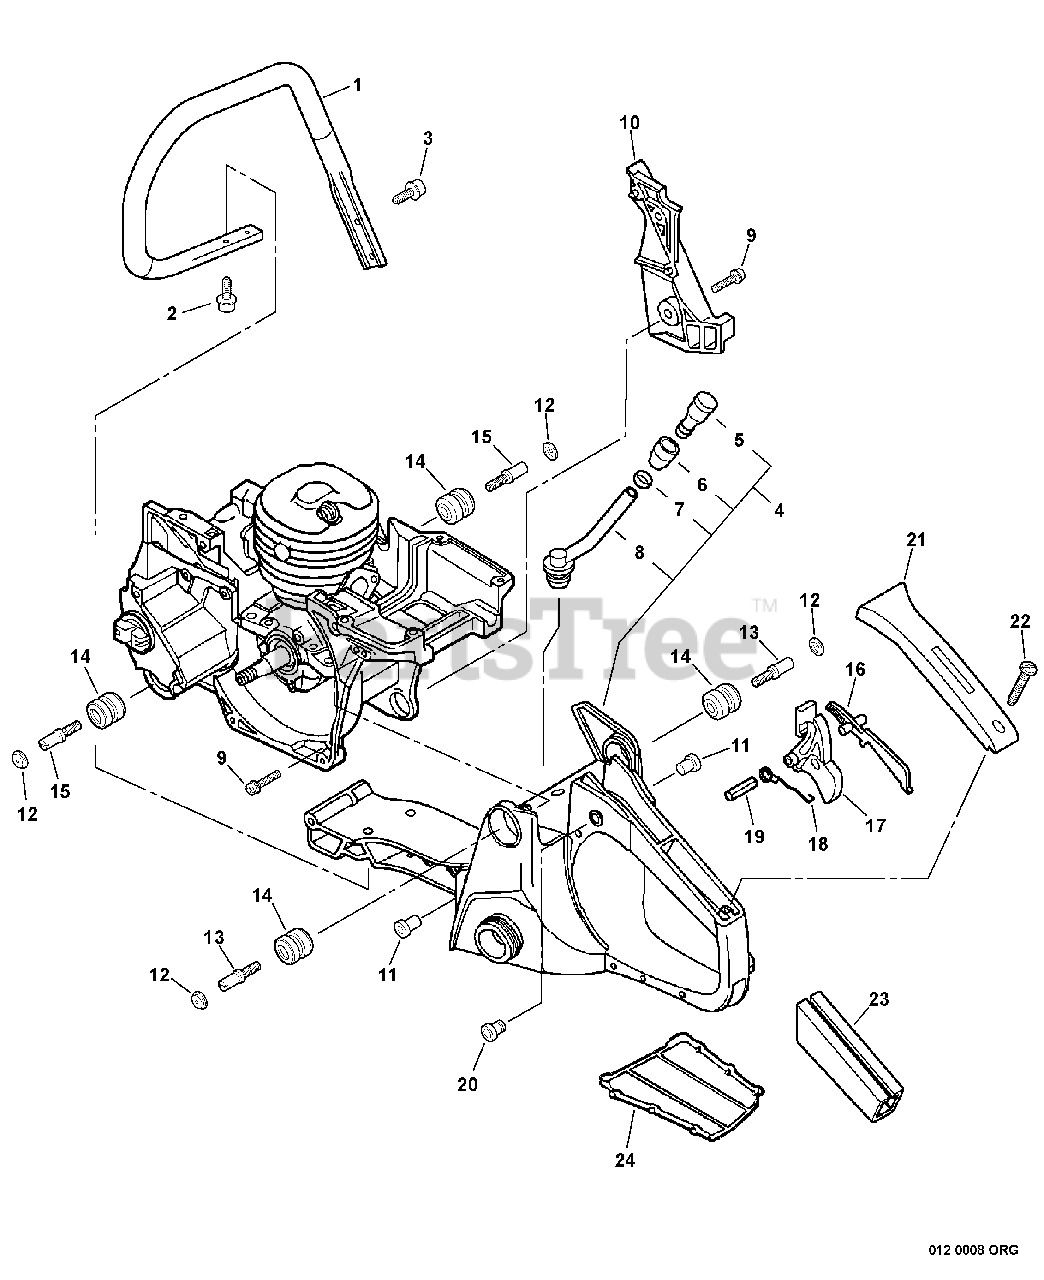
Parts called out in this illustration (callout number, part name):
1	HANDLE - FRONT
2	SCREW - 5X16
3	SCREW - 5X20 -- TAPPING
4	HANDLE ASSY - REAR
5	VENT, FUEL TANK
6	COVER, VENT
7	CLIP - 6.5
8	PIPE - VENT
9	SCREW - 5X16
10	GUARD, SPROCKET
12	CAP, CUSHION
16	LEVER, TRIGGER LOCKOUT
17	TRIGGER, THROTTLE
18	SPRING, TRIGGER
19	PIN - SPRING -- 4X30
21	COVER, HANDLE
22	SCREW - 4X14
23	GRIP, HANDLE
24	SHIELD, SNOW
